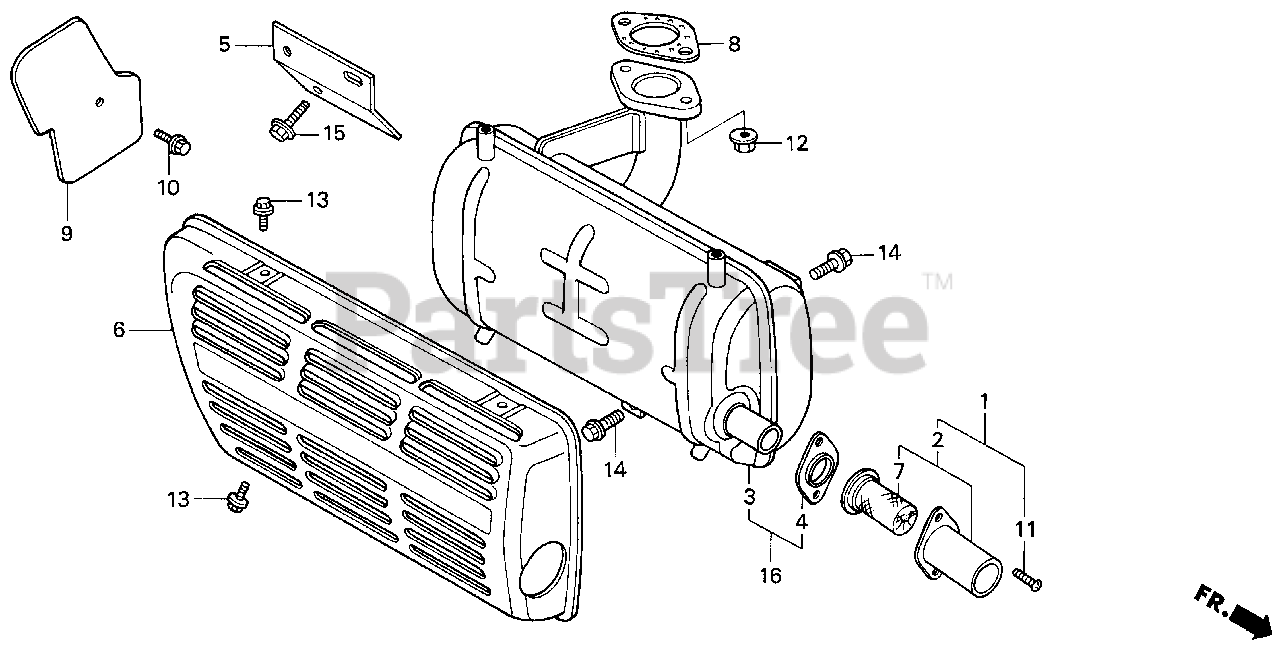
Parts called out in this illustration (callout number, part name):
1	ARRESTER KIT
2	CAP SET, ARRESTER
4	BASE, ARRESTER
5	PLATE, MUFFLER SUPPORT
6	PROTECTOR, MUFFLER
7	ARRESTER, SPARK
8	GASKET, MUFFLER
9	GUIDE, AIR
10	BOLT-WASHER (6X12)
11	SCREW, PAN (5X8)
12	NUT, FLANGE (8MM)
13	BOLT, FLANGE (6X10)
14	BOLT, FLANGE (8X14)
15	BOLT, FLANGE (8X20)
